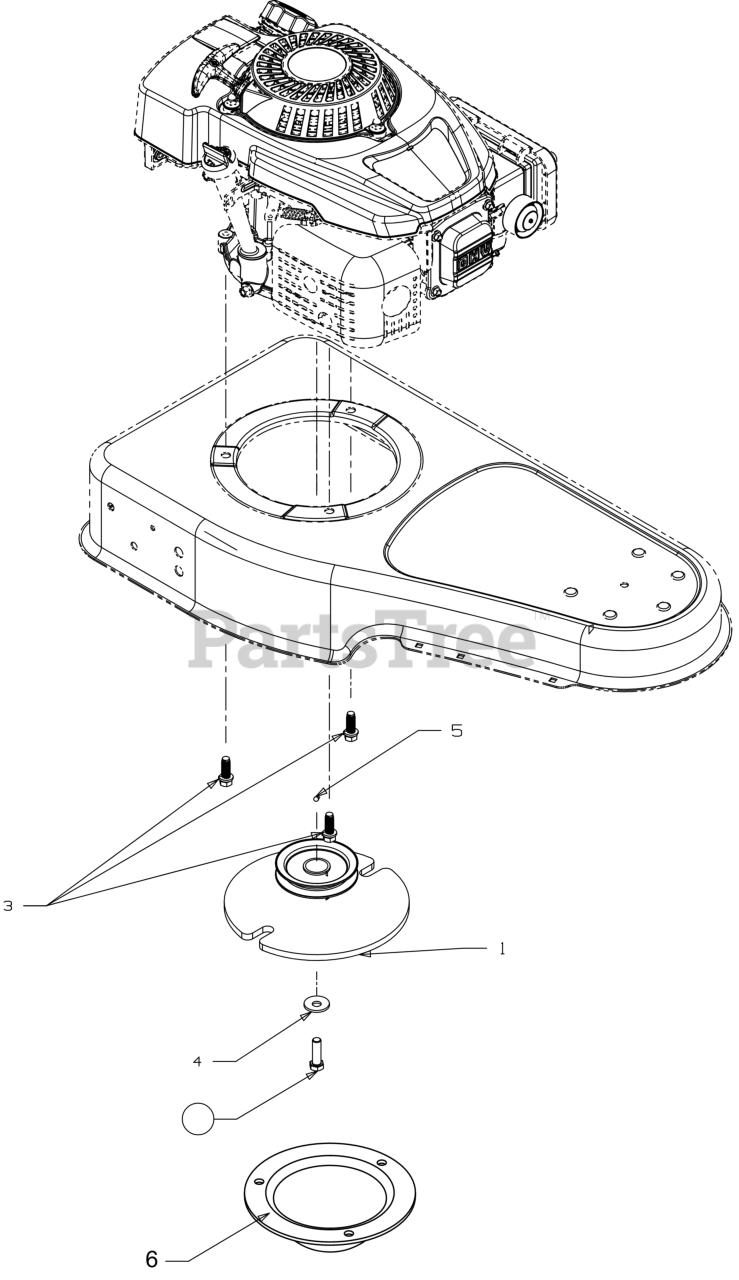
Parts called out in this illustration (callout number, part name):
1	FLYWHEEL PULLEY
2	SCREW 3/8-24 x 1.25 GR8
3	SCREW 3/8-16 x 1
4	BELL WASHER
5	GREASE
6	SKID ASSEMBLY
